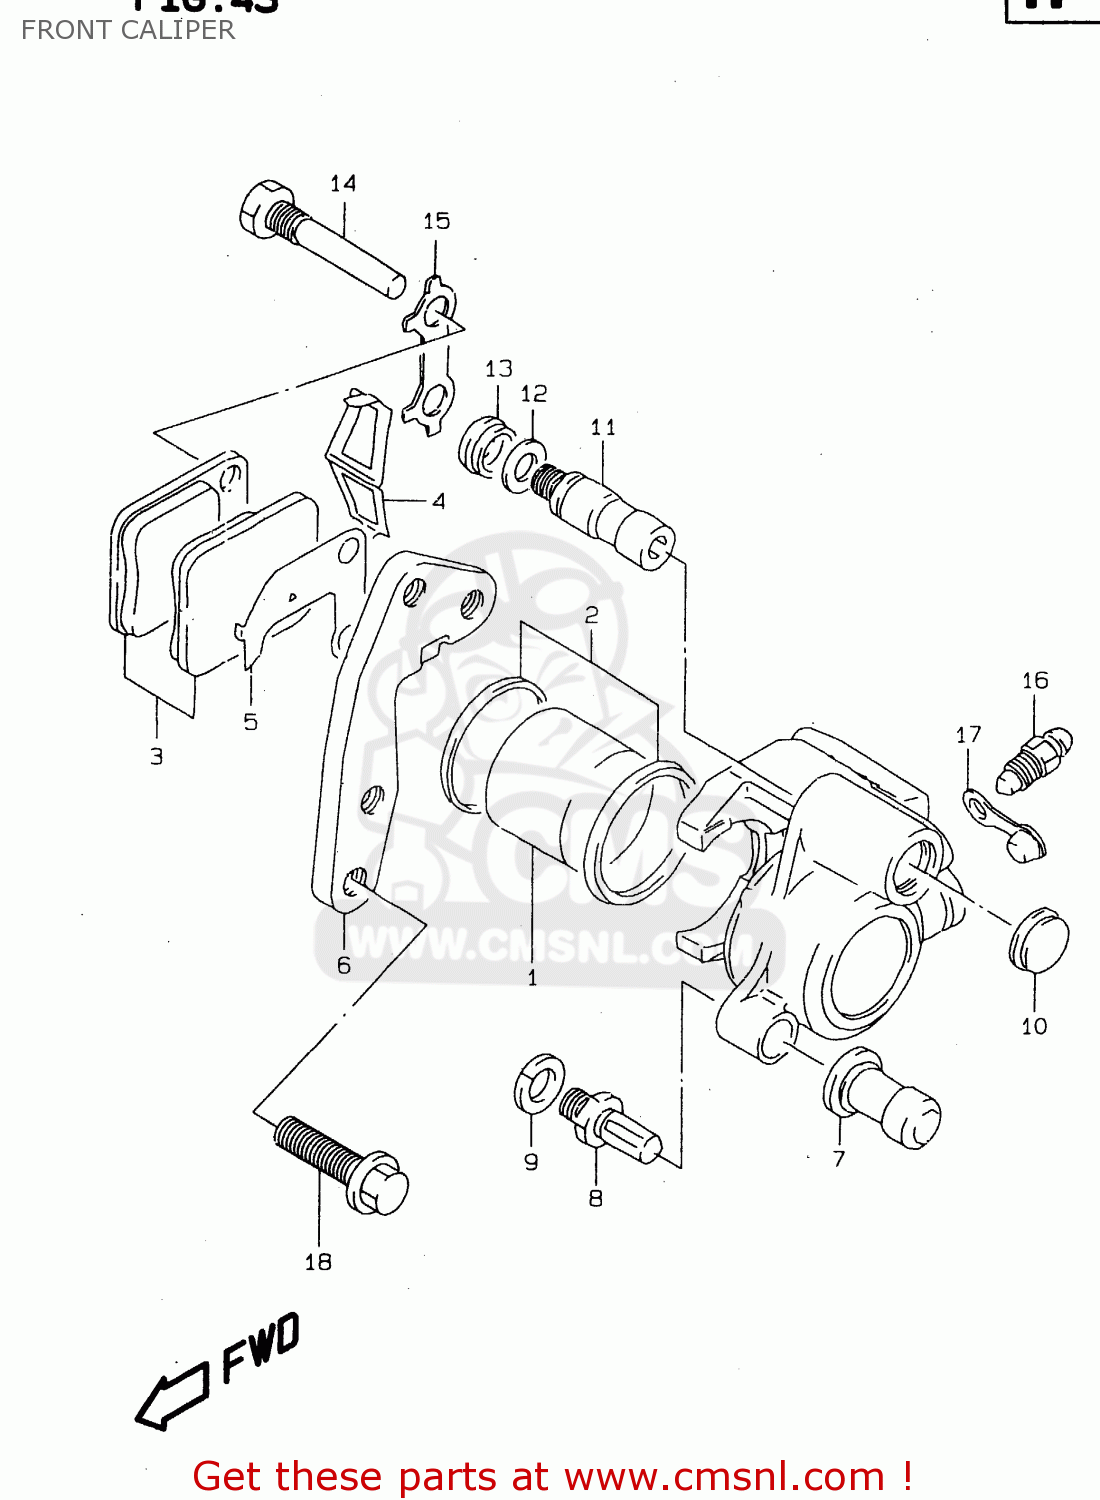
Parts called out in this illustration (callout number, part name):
1	PISTON SET,CALIPERS
2	SEAL SET,PISTON
3	PAD SET (NAS)
4	SPRING,PAD
5	SHIM
6	BRACKET
7	BOOT
8	BOLT,PIN
9	WASHER,WAVE
10	DUST SEAL
11	PIN,SLIDE
12	SPRING,FRICTION
13	BOOT,PIN
14	PIN,HANGER
15	WASHER
16	BLEEDER
17	CAP,BLEEDER
18	BOLT(8X30)
